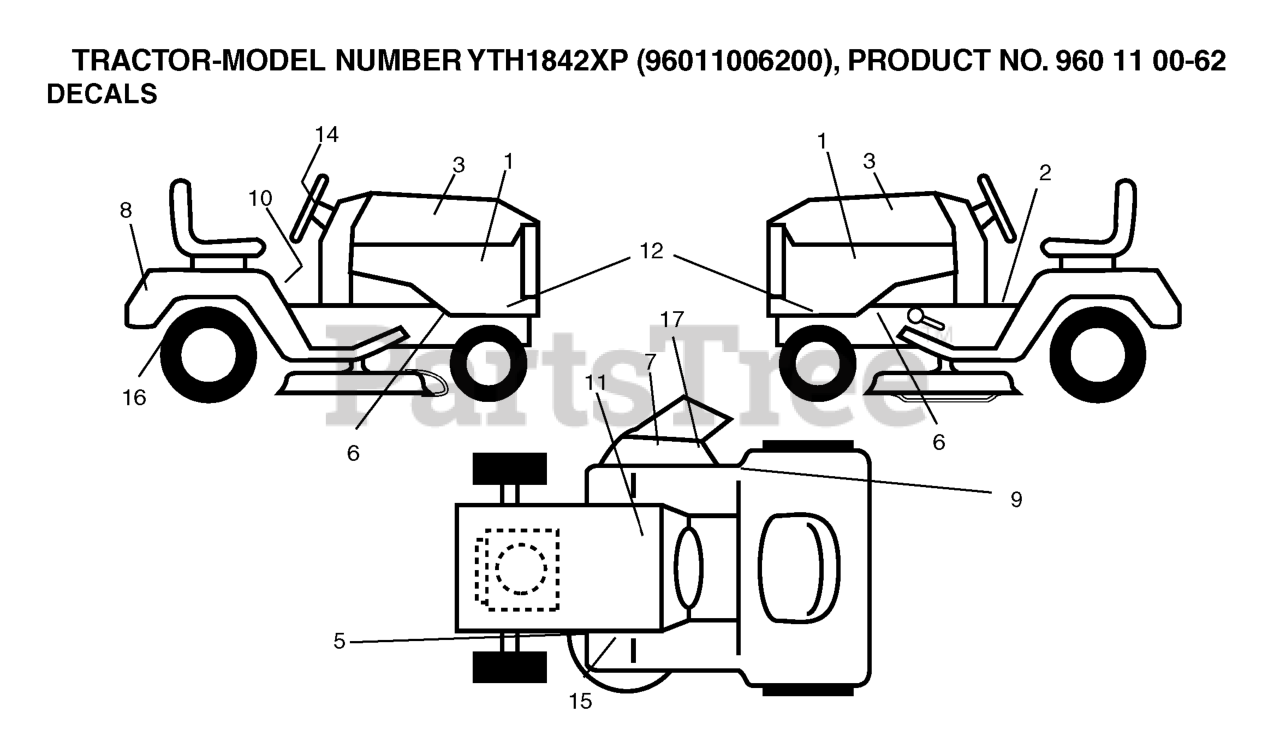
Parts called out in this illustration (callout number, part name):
1	DECAL.HOOD.HUSQVARNA.INTERNATI
2	DECAL PARK BRAKE
5	DECAL V BELT SCHEMATIC
7	DECAL.INTERNATIONL.CUTFINGER
9	DECAL
10	DECAL READ OWNER'S MAN SYMS
11	DECAL BTRY SYMBOLS
14	DECAL.STEERING.HUSQ.BLUE
15	DECAL
16	DECAL
17	DECAL DECK "B" 42"
